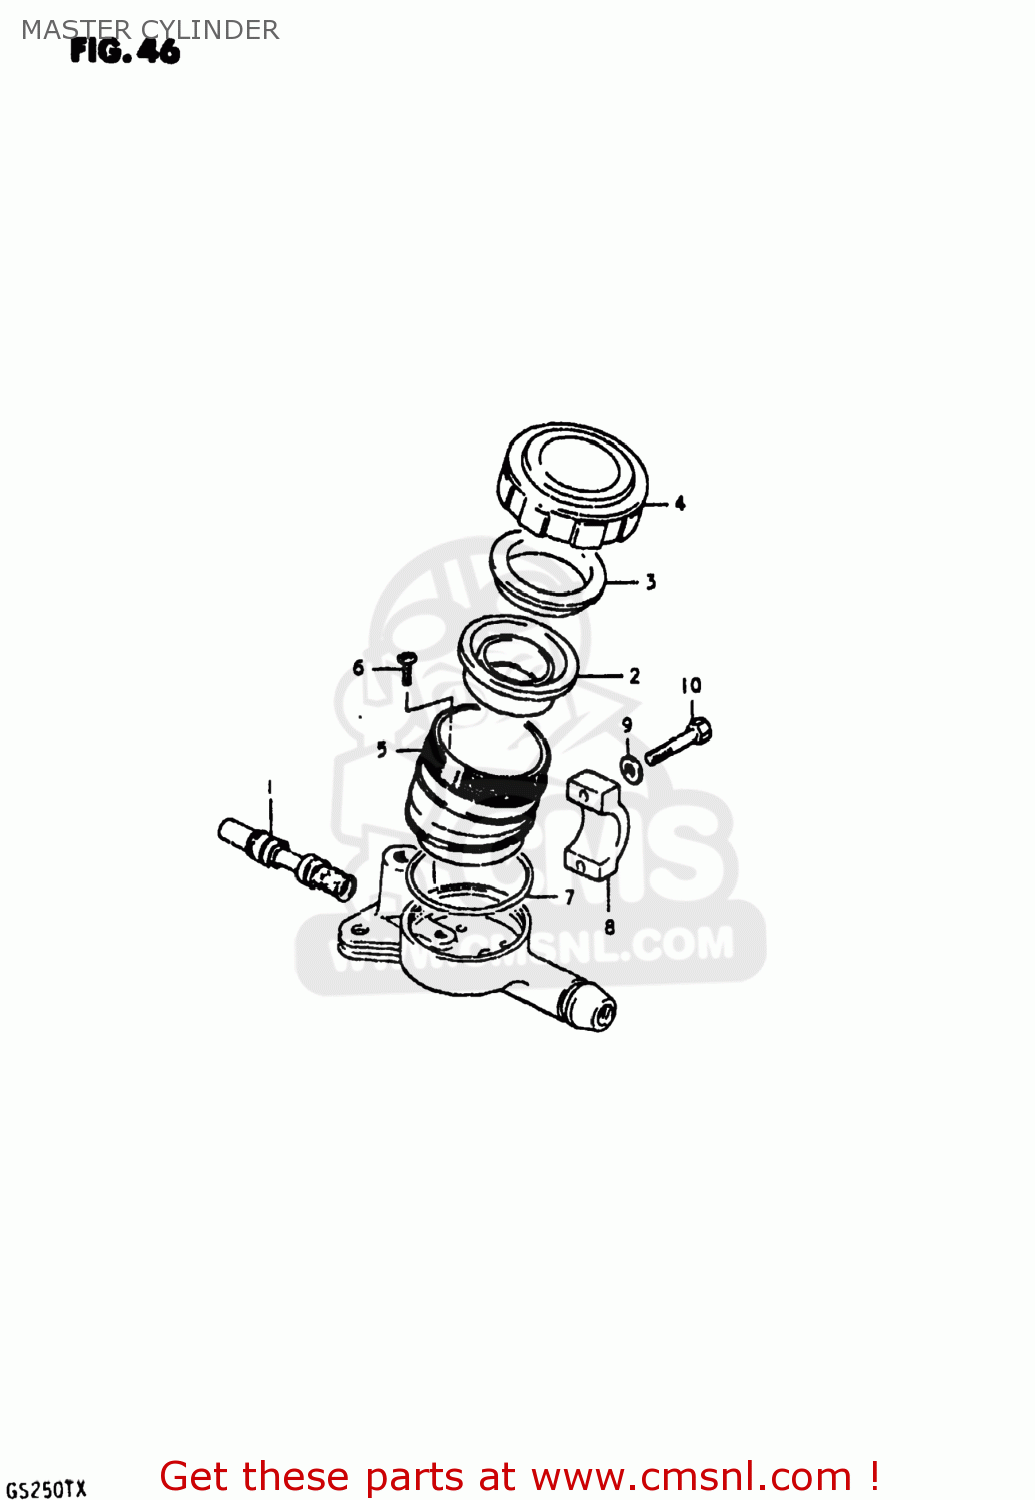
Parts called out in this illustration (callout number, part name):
1	PISTON & CUP SET
2	DIAPHRAGM
3	PLATE,DIAPHRAGM
4	CAP
5	RESERVOIR
6	SCREW,MASTER CYLINDER
7	O RING
8	HOLDER,MASTER CYLINDER
9	WASHER
10	BOLT
